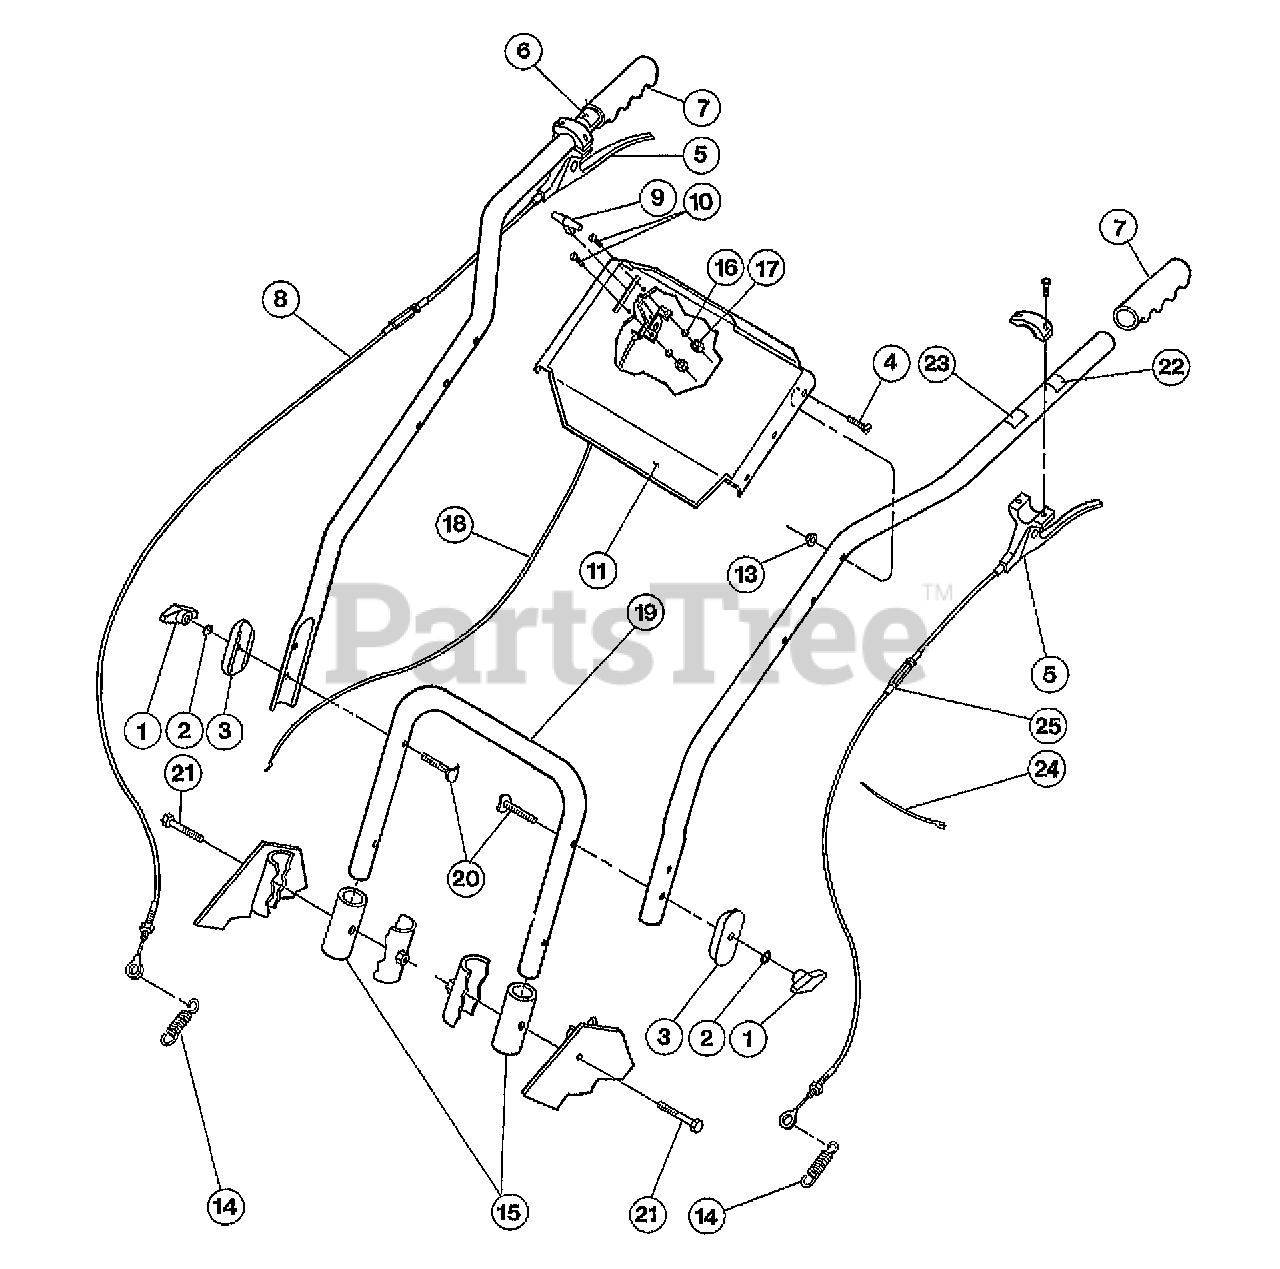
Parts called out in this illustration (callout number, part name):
2	WASHER-LOCK INT/EXT
3	CLAMP-H/BAR #40100P
4	BOLT-SLPH-1/4-20X1 3/8 ZP
5	LEVER-CONTROL T/BLAZER (WITHOUT CABLE)
6	DECAL-BLADE DRIVE LEVER
7	GRIP-H/B 1" PONY/P-J OPC
8	CABLE-CUTTERBAR
9	KNOB-THROTTLE CABLE
10	SCR-RH M10-32X.5 MACH (THROTTLE LEVER)
11	DECAL-CONTROL PANEL T/BLZ
13	NUT-LK 1/4-20
14	SPRING-CABLE
15	SLEEVE-RUBBER LWR H/B
16	WASHER-LK M10
17	NUT-HH M10-32X.125
18	CABLE-THROTTLE CONTROL
19	HANDLEBAR-LWR #40072P
20	BOLT-CH 5/16-18 X 2 ZP
21	SCR-HF 5/16-18X2.25 G5
22	DECAL-WHEEL DRIVE LEVER
23	DECAL-STABIL STARTING
24	TIE-CABLE NYLON BLACK
25	CABLE-WHEEL DRIVE
